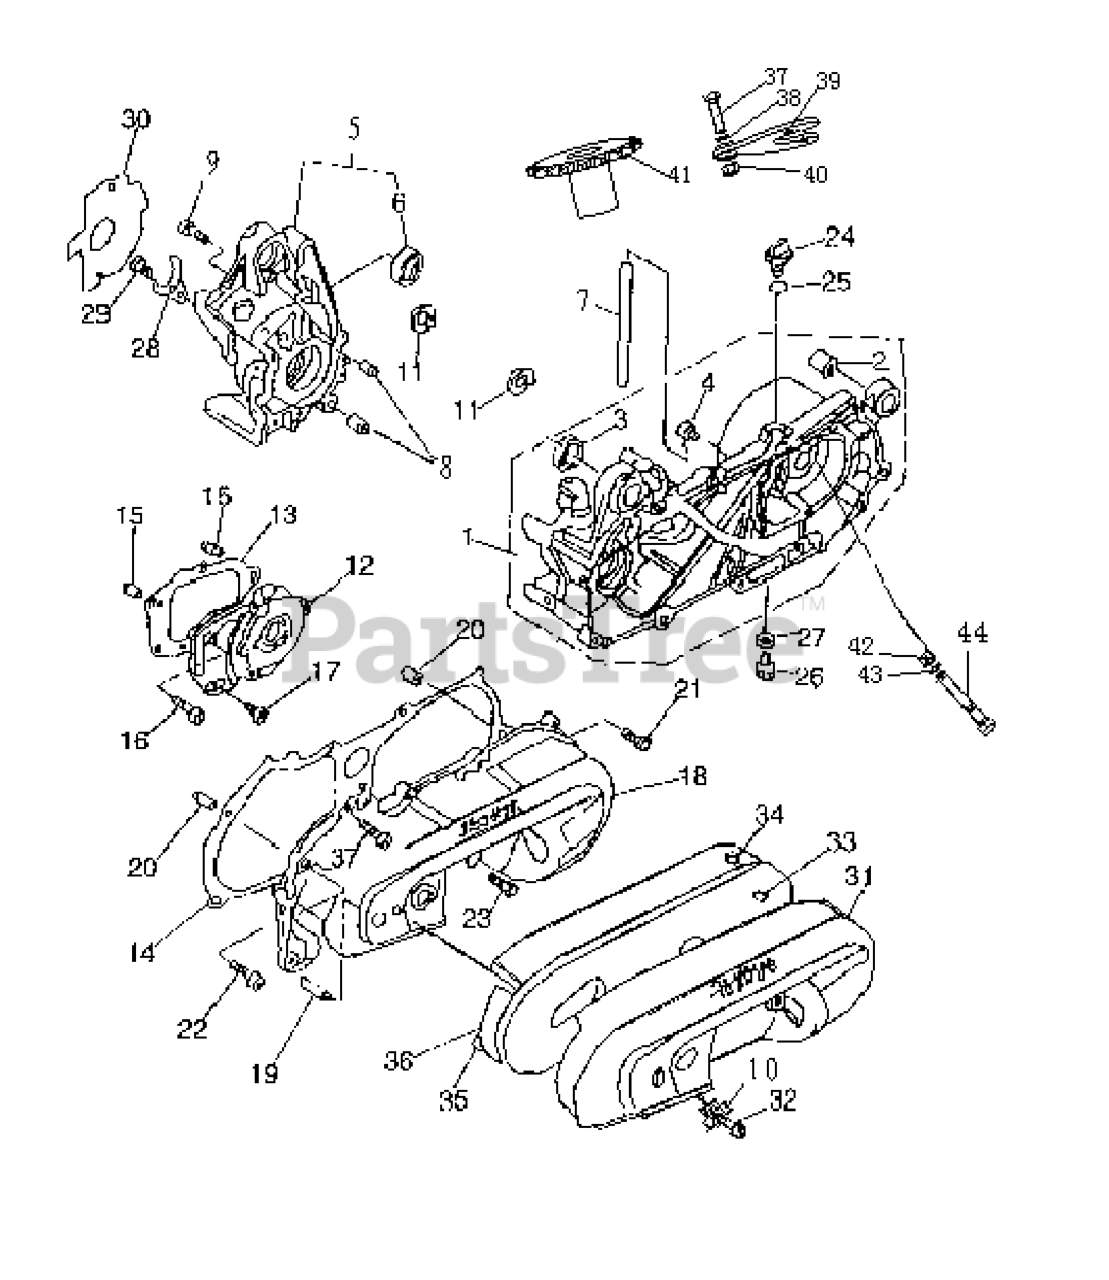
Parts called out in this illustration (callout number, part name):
1	CRANKCASE, LH. AND RH.
2	GROMMET
3	GROMMET
4	BREATHER PLUG
6	GROMMET
8	DOWEL PIN
10	NUT BUSH, RUBBER
11	CIRCLIP
12	CRANKCASE COVER
13	GASKET, GEAR BOX
14	GASKET SIDE COVER
15	DOWEL PIN
18	SIDE COVER
20	DOWEL PIN
24	OIL PLUG
26	FLANGE BOLT
31	PROTECTING COVER
33	GASKET
34	GASKET
35	GASKET
36	GASKET
39	BRACKET ASSY
41	CHAIN WHEEL ASSY (15T)
